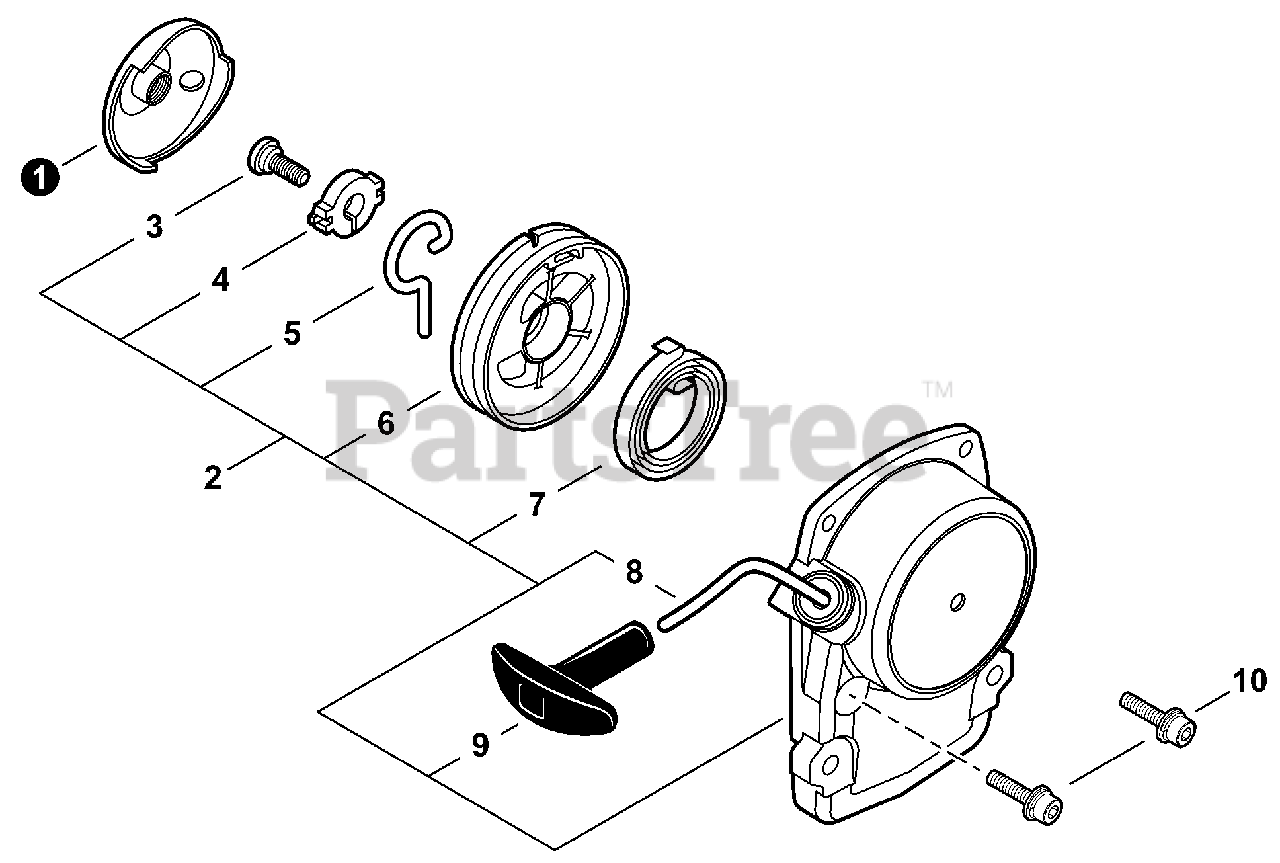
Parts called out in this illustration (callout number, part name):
1	PULLEY, STARTER
2	STARTER ASSY, RECOIL
3	SCREW 5
4	WASHER 5
5	ARM, SWING
6	REEL, ROPE
7	SPRING, RECOIL
8	ROPE, STARTER Ø3×850
9	GRIP, STARTER
10	BOLT M4×16
